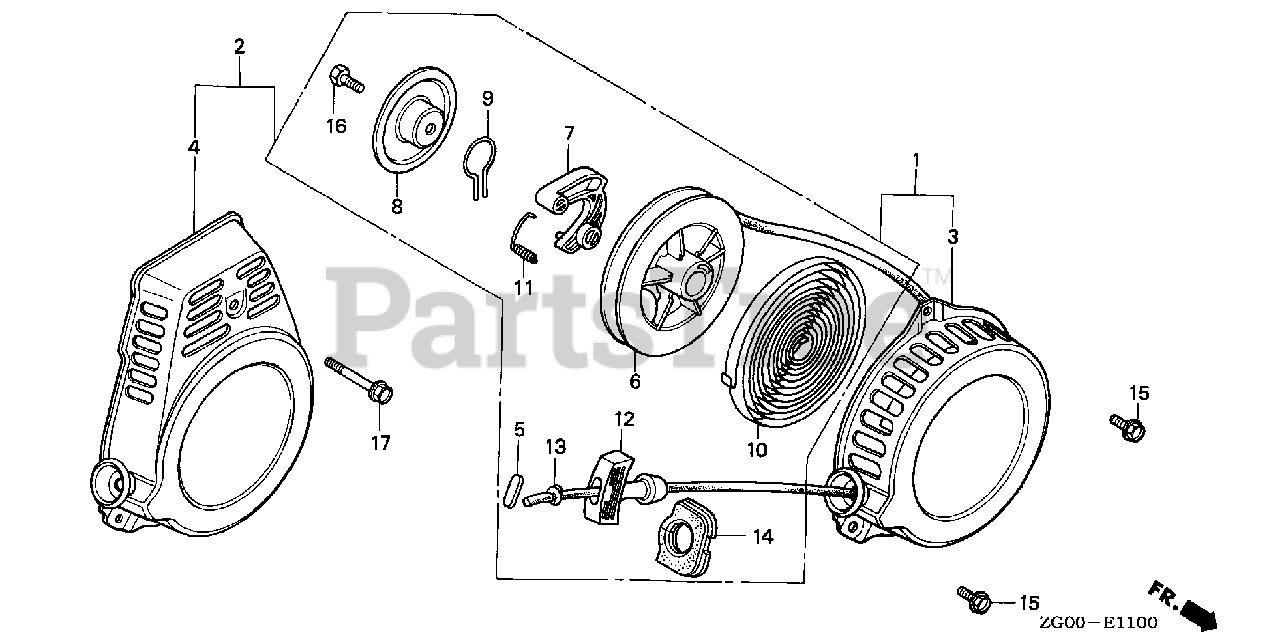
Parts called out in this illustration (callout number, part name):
1	STARTER ASSY., RECOIL
3	CASE, STARTER
6	PULLEY, RECOIL STARTER
7	RATCHET, STARTER
8	PLATE, FRICTION
9	SPRING, FRICTION
10	SPRING, RETURN
11	SPRING, RETURN
12	KNOB, STARTER (NOT AVAILABLE)
13	ROPE, RECOIL STARTER (#4X55")
15	BOLT, FLANGE (6X8)
16	BOLT, HEX. (6X20)
